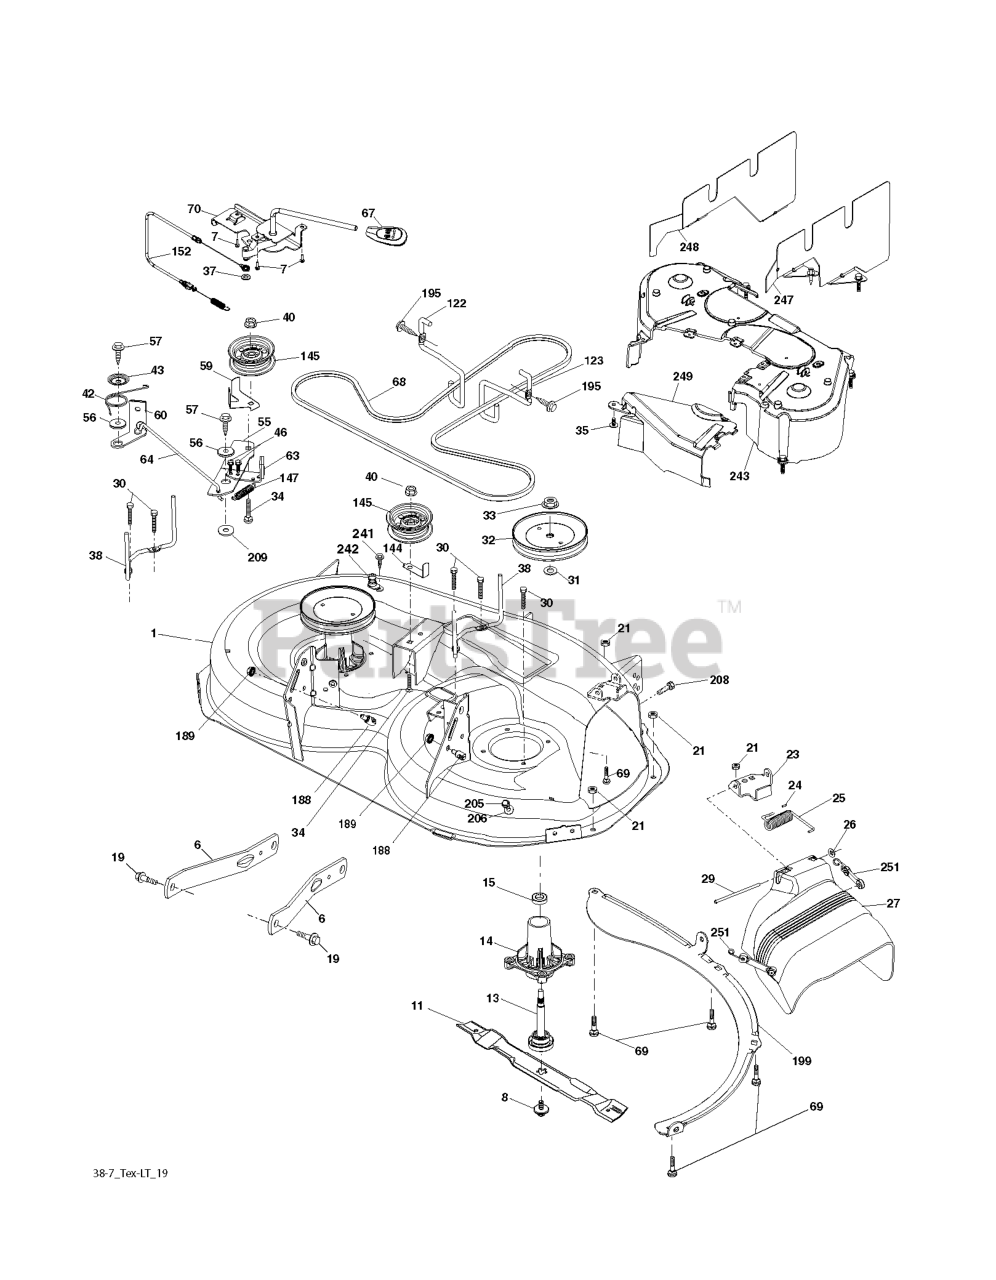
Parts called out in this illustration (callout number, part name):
1	HOUSING
6	ARM.SUSPENSION.MOWER.R
7	SCREW.#10 X 0.750.BOS
8	BOLT.WASHER.ASM.7/16-2
11	BLADE 38" PREMIUM
13	SHAFT.ASM.MDRL.N/GREASE.38
14	RP.HOUSING.MANDREL.4PT.
19	BOLT.SHOULDER
21	LOCKNUT
23	BRKT.DEFLECTOR.38"2005+
24	CAP-SLEEVE LT
25	SPRING.TORSION.DEFLECT
26	NUT PUSH M
27	SHIELD ASM.DFLCTR MWR.38-7"BLK
29	ROD.HINGE
30	SCREW, WASHER HEAD
31	WASHER.SPACER.MANDREL
32	PULLEY.MANDREL.5.0.PD.38"
33	NUT.FLANGE.LOCK.TOP
34	BOLT.3/8-16X1.50
35	FASTENER.XMAS.TREE
37	WASHER
38	KEEPER BELT LH MANDREL
40	NUT LOCK FLG 3/8-16 UNC
42	SPRING.TORSION.BRAKE
43	SRPING.TORSION.RETAINE
46	SCREW.1/4-20X5/8
56	SPACER.RETAINER
57	SCREW 3/8-16X1
59	GUARD, BELT
60	ARM BRAKE MOWER RH 38"
63	RP ARM.BRAKE.MOWER.38"LH.TEX
64	LINK BRAKE
67	HANDLE.CLUTCH.CABLE.LT
69	BOLT
70	CLUTCH.ASM.MANUAL.LT.PRED
122	KEEPER BELT ENGINE LH
123	KEEPER BELT RH
144	KEEPER BELT
145	PULLEY.IDLER.48"PRIMARY
147	SPRING RETURN
152	CLUTCH CABLE
188	STUD.FASTNER.W/ANTI-ROTATE
189	NUT LOCK HEX FLANGE 5/16-18
195	SCREW, 3/8-16X3/4
199	BAFFLE.VORTEX.FRONT.38"
205	SCREW
208	SCREW 3/8-16X1/2
209	WASHER 12/32X2X10GA
241	SCREW.TT.#10-32X.5.3/8.FLANGE
242	PORT.WASHOUT
247	SHIELD LEFT
248	SHIELD RIGHT
249	COVER CABLE CLUTCH
251	ELASTIC STRAP KIT
